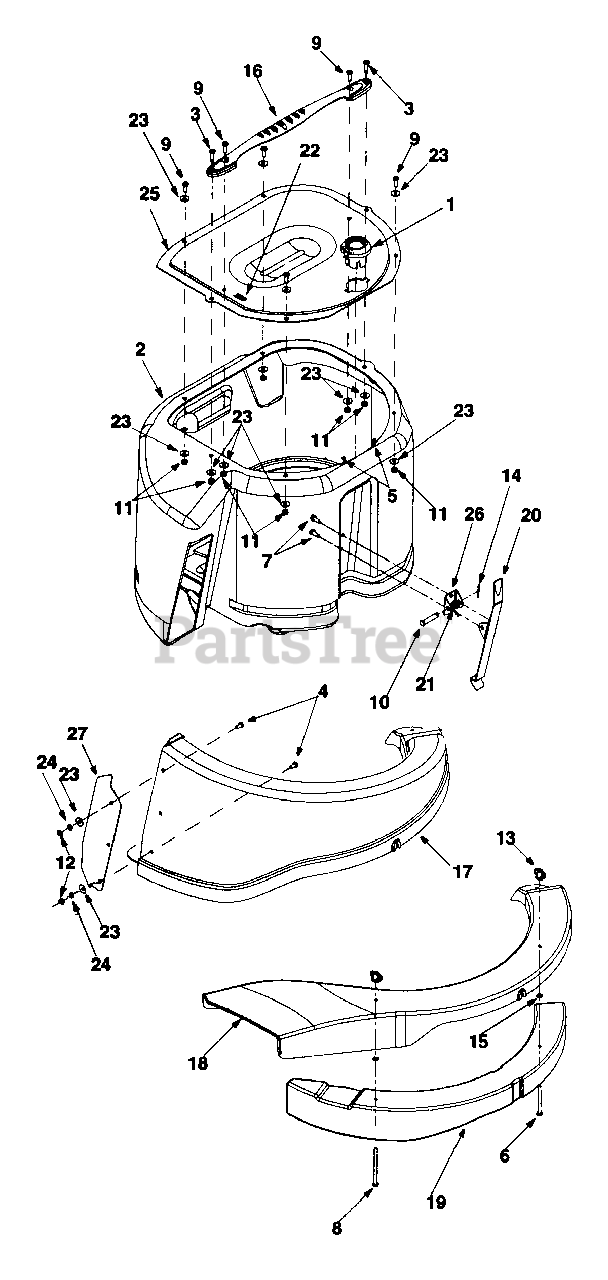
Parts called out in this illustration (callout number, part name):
1	Flow Indicator Assembly
2	Grass Bag Assembly
3	Machine Screw 1/4-20 x 1.0
4	Machine Screw 1/4-20 x 0.5"
5	Hex Screw #10-16 x 0.5"
6	Hex Screw 1/4-20 x 2.7'
7	Self-Tapping Screw 1/4-20 x 0.75"
8	Hex Screw 1/4-20 x 3.75
9	Machine Screw 1/4-20 x 0.75"
10	Clevis Pin
11	Hex Sems Nut 1/4-20
12	Jam Nut
13	Wing Nut
14	Cotter Pin
15	Speed Nut
16	Bag Handle
17	Discharge Chute: Grass Bag
18	Side-Discharge Chute
19	Mulching Plug
20	Bag Release Lever
21	Torsion Spring
22	Clip Spring
23	Flat Washer
24	Lock Washer
